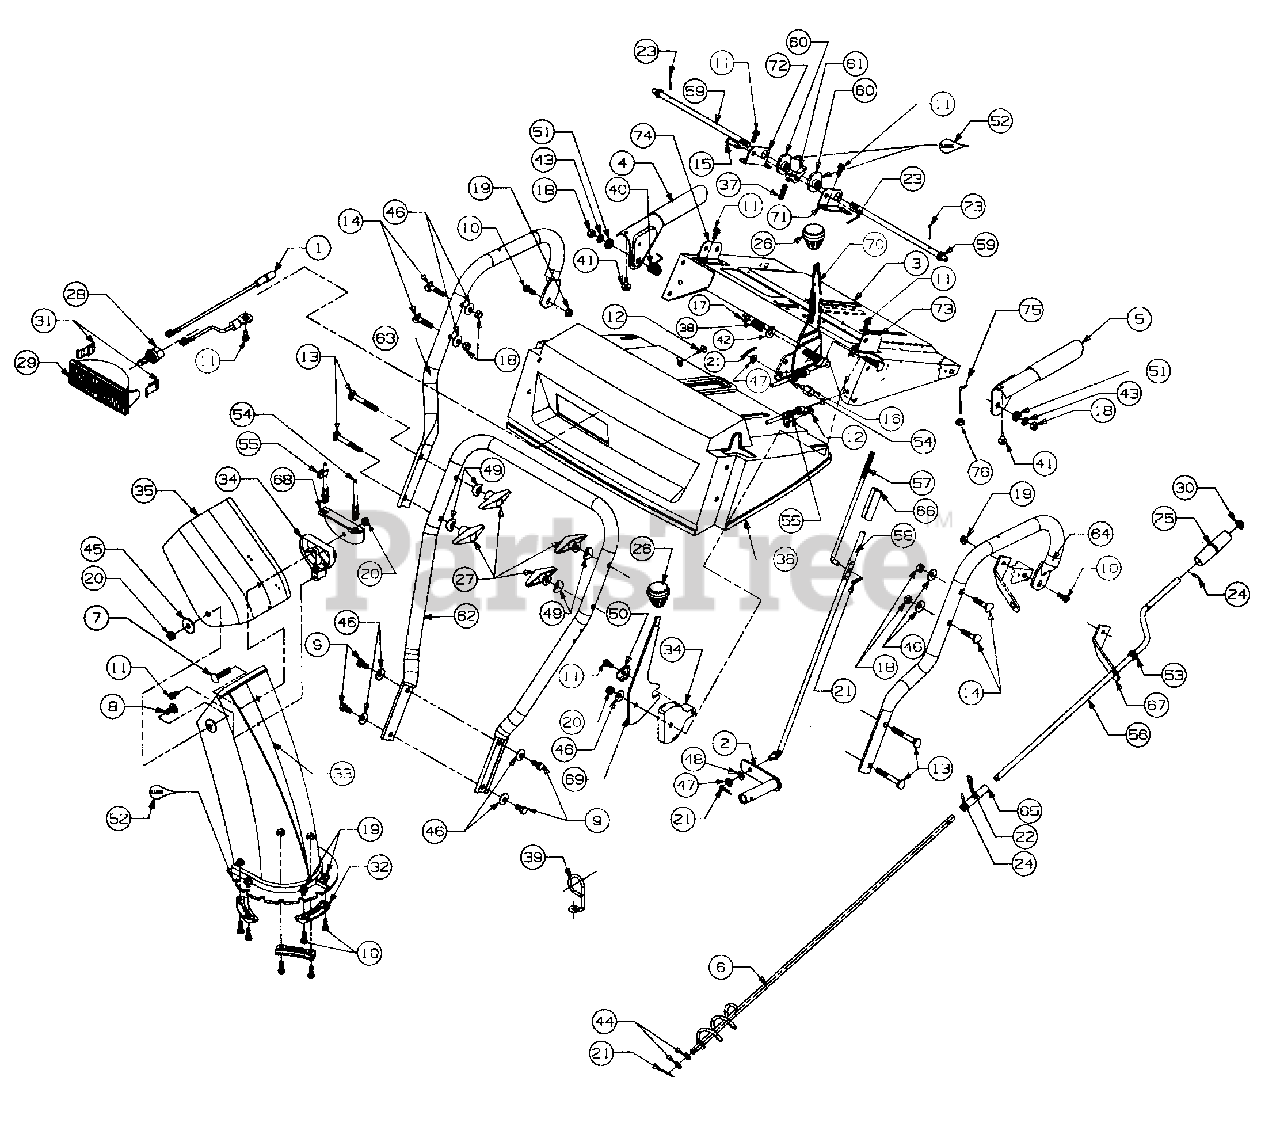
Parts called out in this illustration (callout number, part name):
1	Harness, Light
5	Handle, Engagement-L.H.
8	Bolt, Carriage, 5/16-18 x .75
9	Screw, Hex Cap, 5/16-18 x .75
10	Screw, Hex Cap, 1/4-20 x .75 GR5
11	Screw, Hex Wash Hd Tapp 1/4-14 x .625
12	Screw, Hex Wash Hd Tapp #10-16 x .62
13	Bolt, Curved Hd Carriage 5/16-18 x 2.5
14	Bolt, Curved Hd Carriage 5/16-18 x 1.5
15	Pin, Clevis
16	Ferrule
17	Nut, Hex Insert Lock, 3/8-24
18	Nut, Hex, 5/16-18
19	Nut, Hex Flange Lock, 1/4-20
20	Nut, Hex Patch Lock, 5/16-18
21	in, Internal Cotter
22	Pin, Internal Cotter
23	Pin, Cotter, 3/32 x .75
24	Pin, Roll, 1/8 x .63
25	Knob, Chute Crank
26	Knob, Shift
27	Knob, Wing Nut
28	Lamp
29	Housing, Lamp
30	Cap, Push
31	Clip, Retaining
32	Keeper, Chute
33	Chute, Lower
34	Guide, Cable
35	Chute, Upper
36	Panel, Handle
37	Spring, Compression
38	Spring, Compression
39	Guide, Control Wire
40	Spring, Torsion
42	Washer, Bell, .401 x .87 x .063
43	Washer, Lock, 5/16
44	Washer, Flat, .385 x .62 x .06
45	Washer, Flat, .344 x .1.12 x .12
46	Washer, Bell, .345 x .88 x .06
47	Washer, Flat, .33 x .63 x .06
48	Washer, Spring, .317 x .62 x .09
49	Washer, Saddle
50	Washer, Spec
51	Washer, Spec
52	Lubricant
53	Bushing, Plastic
54	Cable, Chute Control
55	Cable, Chute Control w/Clip
56	Rod, Chute Crank
57	Rod, Upper Shift
58	Rod, Lower Shift
60	Cam, Handle Lock
61	Pawl, Handle Lock
63	Handle, Upper R.H.
66	Connector, Shift Rod
70	Handle, Shift
75	Cable Z-Fitting
76	Nut, Hex Jam, #10-24
